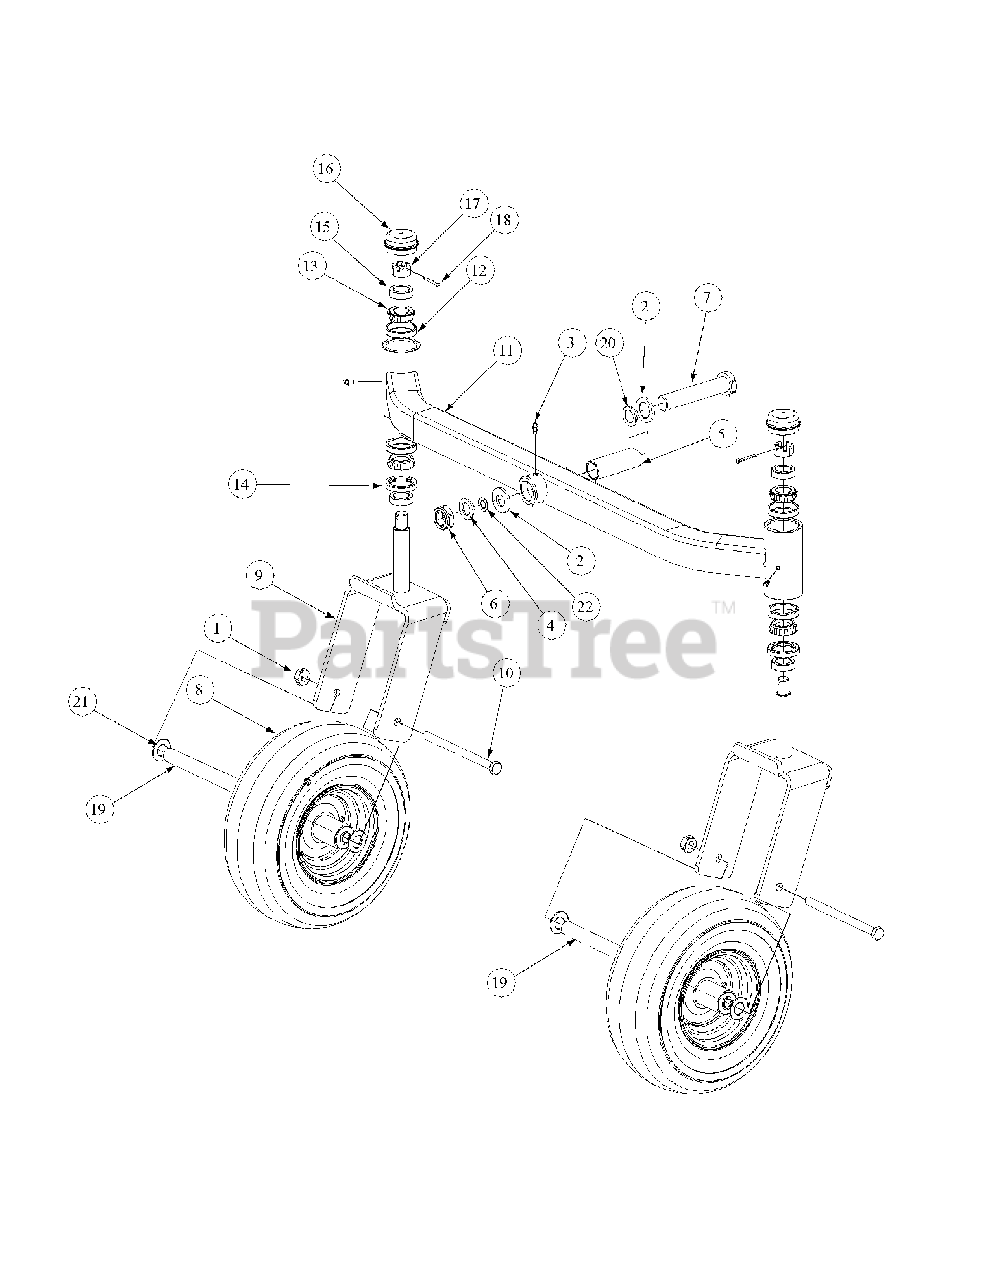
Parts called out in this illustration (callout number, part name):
1	Nut, 1/2-20, Center Lock
2	Bell Washer, 1.25 ID
3	Grease Fitting
4	Special Washer
5	Spacer, 1.005 ID x 1.25 OD x 3.6
6	Nut, Jam, 1.0-14, Insert Lock
7	Hex Cap Screw, 1-14 x 5.0
8	Wheel Assembly, 13 x 6.50 x 6, White, includes:
9	Yoke, Caster Wheel
10	HHCS, 1/2-20, 7.50
11	Front Axle Assembly
12	Cup Bearing
13	Bearing Cone
14	Seal
15	Ring Seal
16	Grease Cap, 1.986 OD
17	Slotted Nut, 3/4-16
18	Cotter Pin, 5/32, 1.25
19	Wheel Spacer
20	Flat Washer, 1.25 ID
21	Spacer, .812 ID x .218LG
22	Retainer Extension, Self Locking
